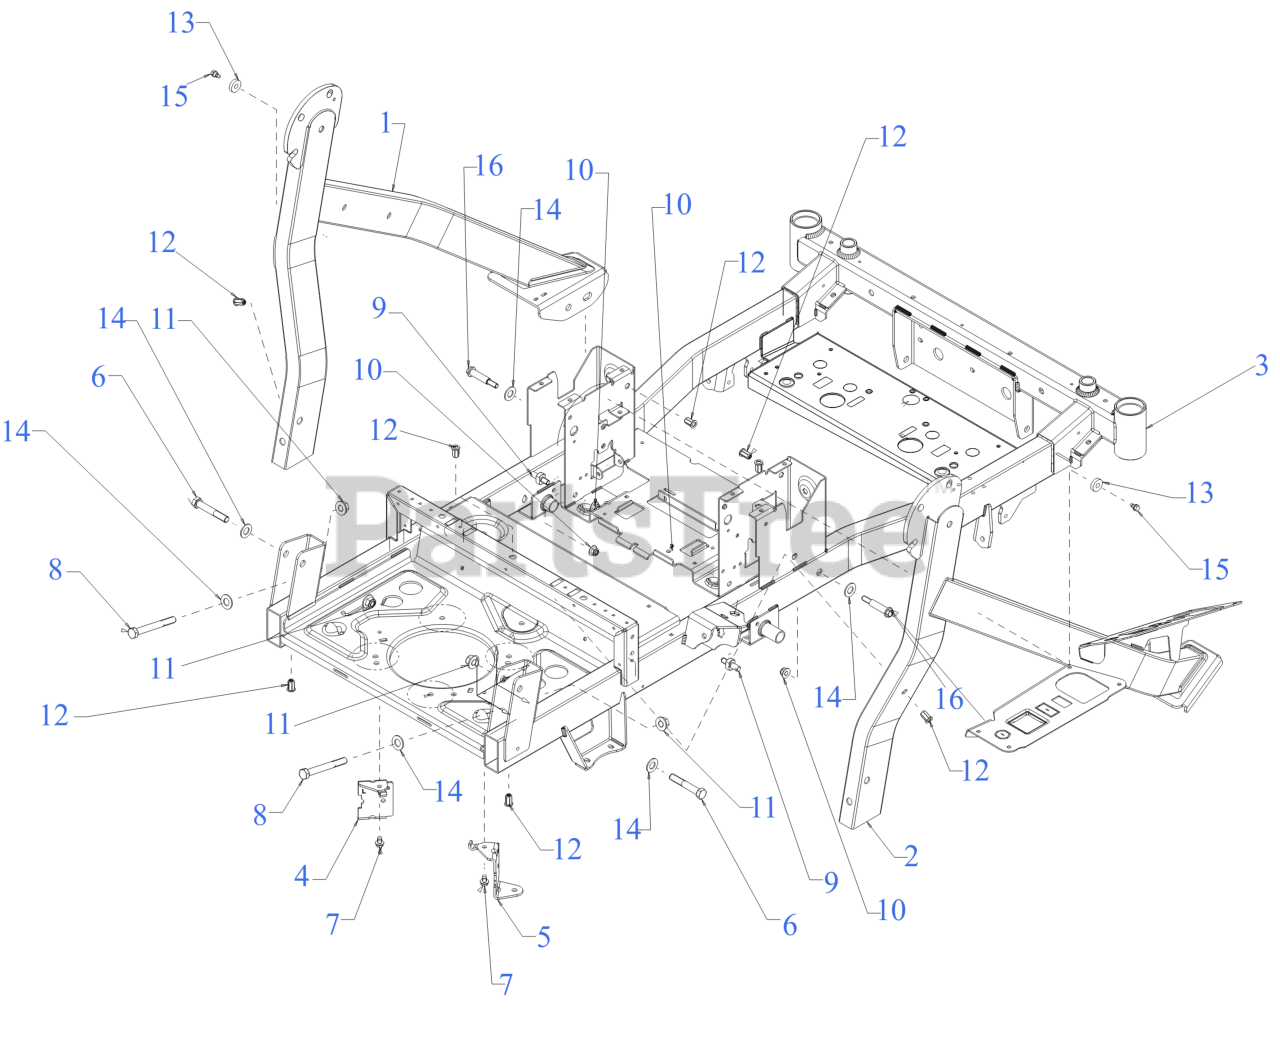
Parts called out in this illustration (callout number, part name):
1	UPPER FRAME (LH)
2	FRAME (UPPER) (RH)
3	FRAME
4	TRANSMISSION SUPPORT (LH)
5	TRANSMISSION SUPPORT (RH)
6	SCREW-HEX 1/2-13 x 3.00
7	SCREW 5/16-18 x .500
8	HEX CAP SCREW 1/2-13x4.25 GR5
9	SHOULDER STUD
12	NUT RIVET 5/16-18
13	NEOPRENE WASHER BUMPER
14	FLAT WASHER
15	SHOULDER SCREW 1/4-20 x .50
16	SHOULDER SCREW .50x1.75 3/8-16
